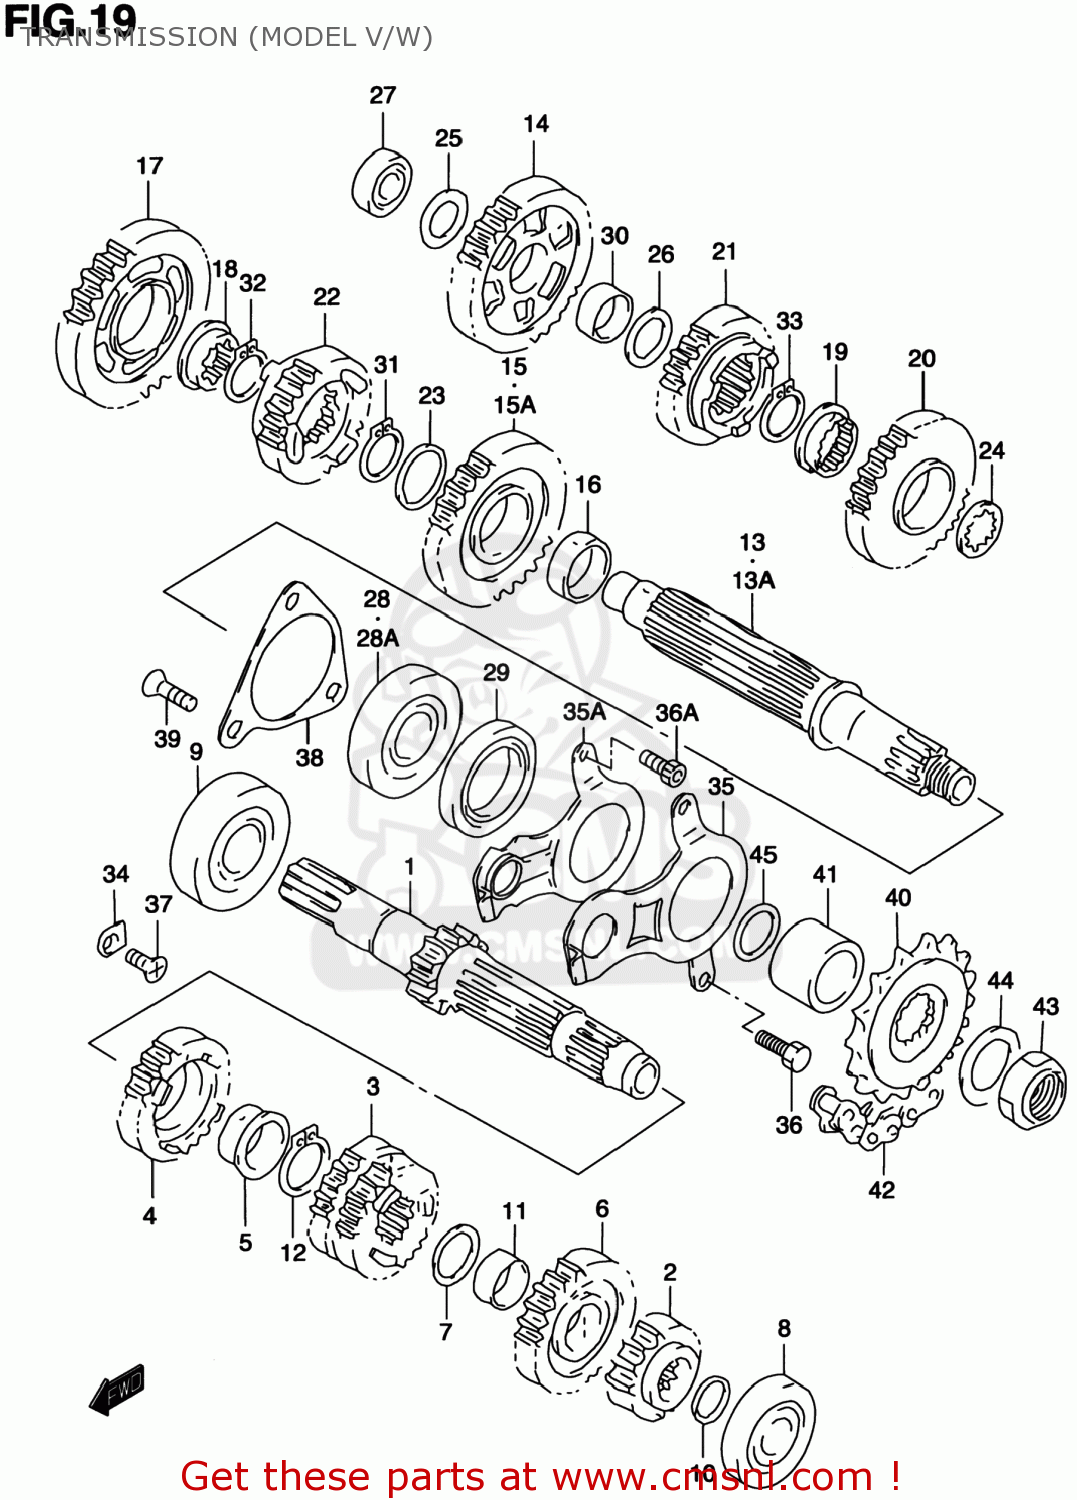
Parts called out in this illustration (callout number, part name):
1	SHAFT,COUNTER (NT:12)
2	GEAR,2ND DRIVE(NT:15)
3	GEAR,THIRD & FOURTH DRIVE,N
4	GEAR,FIFTH DRIVE (NT:23)
5	BUSHING,FIFTH DRIVE GEAR
6	GEAR,SIXTH DRIVE (NT:24)
7	SHIM(22X30X1)
8	BEARING 20X47X14
9	BEARING(25X62X17)
10	O RING(D:1.9,ID:16.6)
11	BUSHING
12	CIRCLIP
13	SHAFT,DRIVE
13A	SHAFT,DRIVE
14	GEAR,1ST DRIVEN(NT:32)
15	GEAR,SECOND DRIVEN (NT:29)
15A	GEAR,SECOND DRIVEN (NT:29)
16	BUSH,2ND DRIVEN GEAR
17	GEAR,THIRD DRIVEN (NT:27)
18	BUSH
19	BUSH
20	GEAR,FOURTH DRIVEN (NT:27)
21	GEAR,FIFTH DRIVEN (NT:25)
22	GEAR,SIXTH DRIVEN (NT:24)
23	WASHER(27X36X1)
24	WASHER,LOCK
25	SHIM(20X34X1)
26	SHIM(22X34X1)
27	BEARING(20X52X15)
28	BEARING(28X68X18)
28A	BEARING(28X68X20)
29	SEAL,OIL(38X52X8)
30	BUSH
31	CIRCLIP
32	CIRCLIP
33	CIRCLIP
34	RETAINER
35	RETAINER,DRIVE SHAFT OIL SEAL
35A	RETAINER,DRIVESHAFT O
36	BOLT
36A	BOLT,STRANGER
37	SCREW
38	RETAINER,DRIVE SHAFT BEARING
39	SCREW(6X12)
40	SPROCKET,ENGINE (NT:17)
41	SPACER,ENGINE SPROCKET
42	CHAIN ASSEMBLY RK50GSVZ1.1
43	NUT
44	SHIM(25X40X1.5)
45	O RING(D:2.4,ID:23.7)
